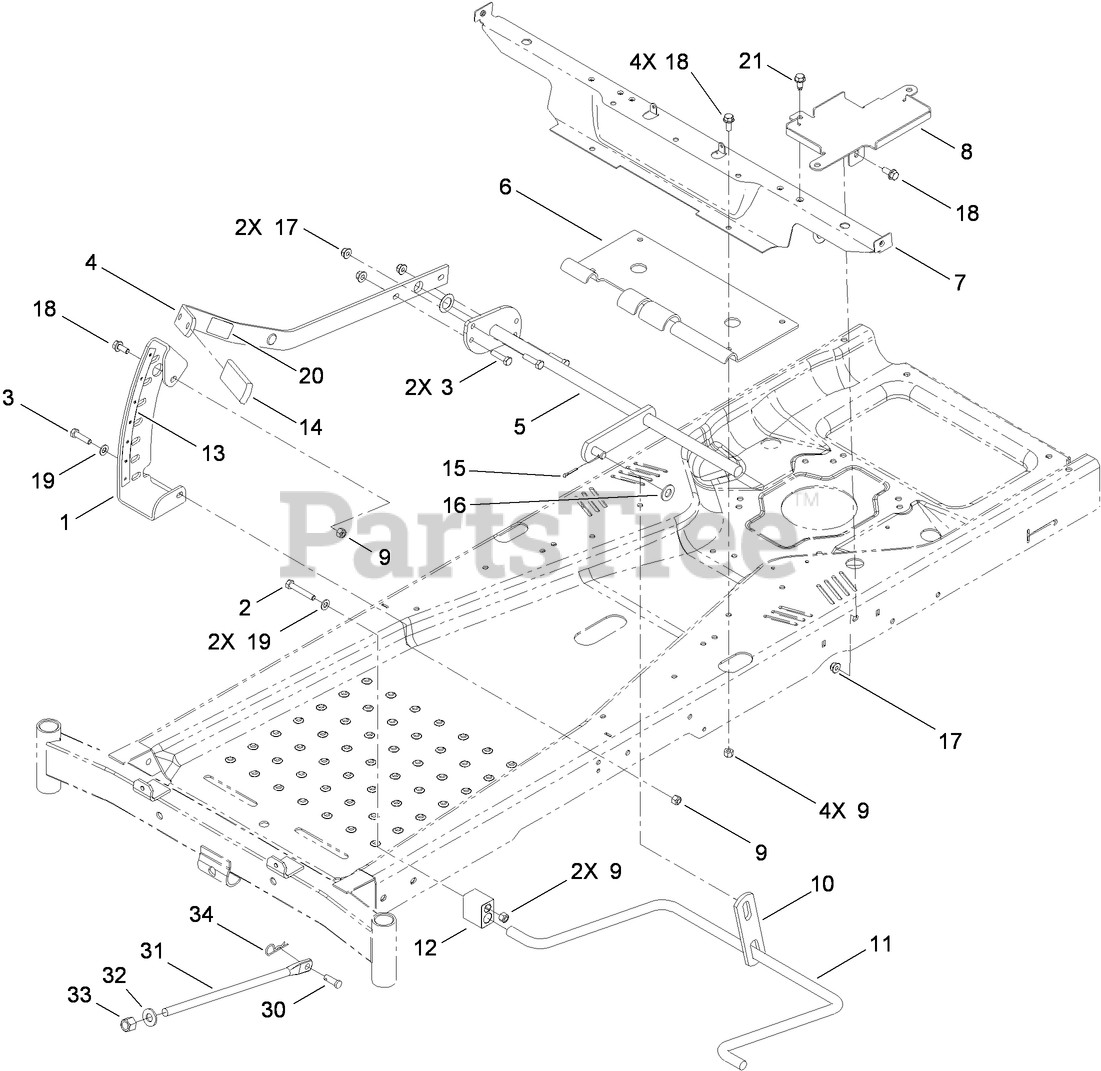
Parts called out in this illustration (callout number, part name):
1	SECTOR-HOC
2	SCREW-HH
3	SCREW-HH
4	LIFT ARM ASM
5	LIFT LEVER ASM
6	PLATE-LIFT
7	BRACKET-SEAT/PODS
8	TRAY-BATTERY
9	NUT-LOCK, NI
10	LINK-LIFT
11	ARM-LIFT, REAR
12	BLOCK-PIVOT
13	DECAL-HOC
14	GRIP-LEVER, LIFT
15	PIN-COTTER
16	WASHER-FLAT
17	NUT-HF, NI
18	SCREW-HHF
19	WASHER-PLAIN
20	DECAL-HOC
21	SCREW-HWH
30	PIN-CLEVIS
31	ROD-LIFT
32	WASHER-THRUST
33	NUT-LOCK, NI
34	PIN-HAIR
